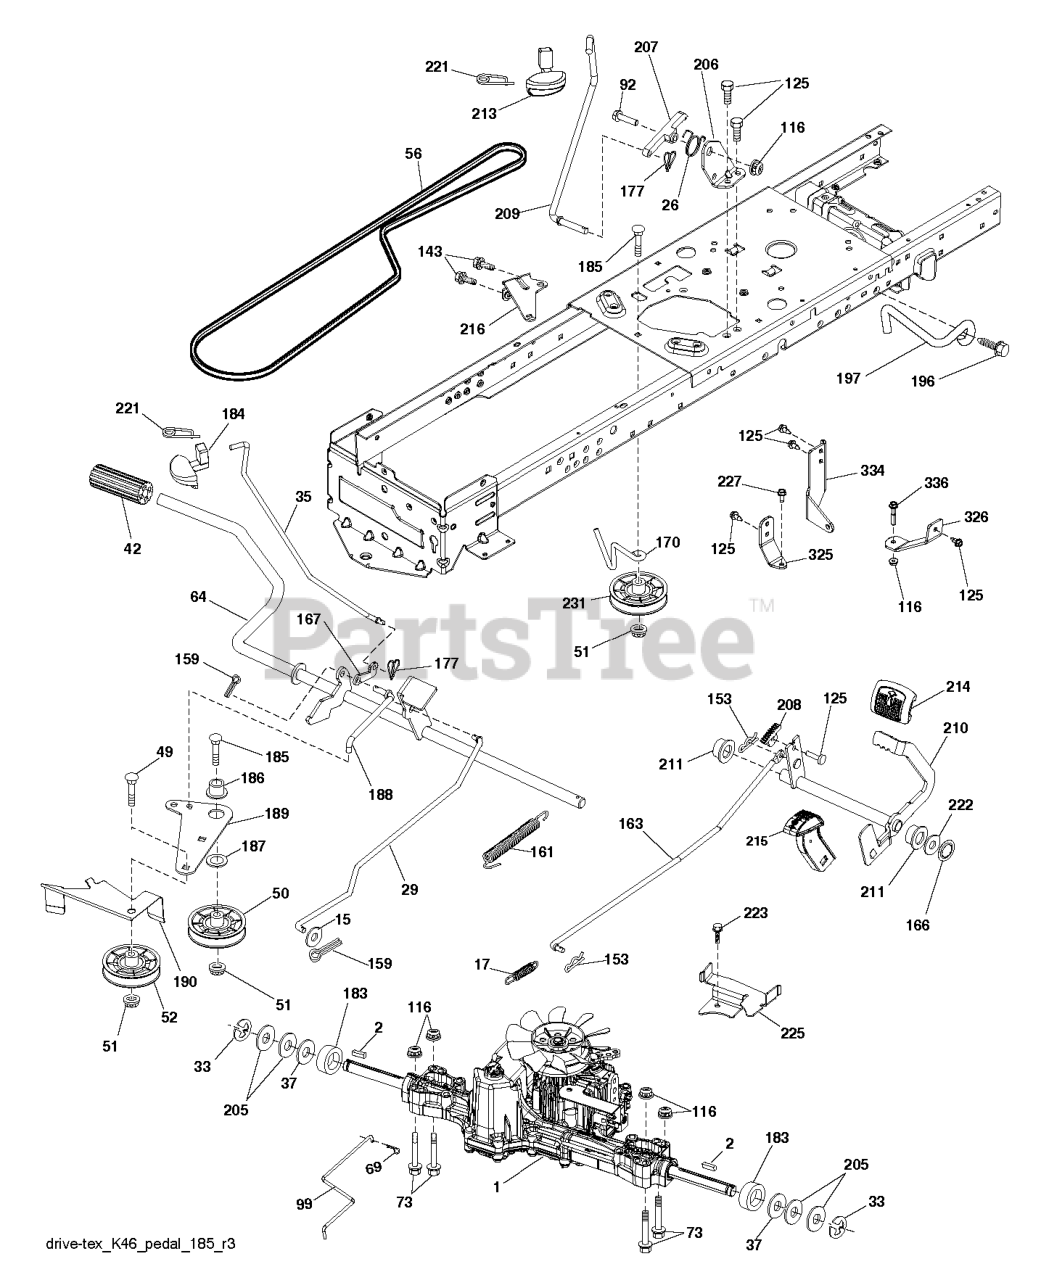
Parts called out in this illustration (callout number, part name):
2	SQUARE KEY
15	WASHER PLAIN WASHER 3/8 X 0.08
17	SPRING.BRAKE.K46.GREEN
26	SPRING.RETURN.CRUISE
29	ROD.BRAKE.K46
35	ROD ROD.PARKINGBRAKE.GT.HUSQ/P
37	WASHER.HARDENED
42	PEDAL COVER
50	IDLER.FLAT.910.OFFSET
51	NUT LOCK FLG 3/8-16 UNC
52	IDLER.V-GROOVE.910.OFFSET
64	SHAFT.ASM.PEDAL.BRK.CNTR
69	HAIRPIN.SOFT.ZINC.059X1.125
99	ARM.PIVOTING.TCRD.GEN2.5.BAGGE
125	SCREW
153	RETAINER M
161	SPRING, RETURN LT
166	NUT.PUSH.625
167	LATCH.BRAKE.SPRING
170	KEEPER.CENTER SPAN.1.688
177	PIN COTTER;LOCKING;BOWTIE;1IN
183	SPACER AXLE
184	HANDLE.PARKING.BRAKE.H (BLK)
186	SPACER.RETAINER
188	LINK.CLUTCH.GROUND DRIVE.LONG
189	BELLCRANK.GROUND.DRIVE.TEX.
190	KEEPER.BELLCRANK.DRIVE
196	SCREW 3/8-16X1
206	BRACKET.MOUNT.CRUISE.LATCH
209	ROD ROD.CRUISECONTROL.GT.HUSQ/
210	ROCKER.ASM.PEDAL.CONTR
211	BEARING.NYLON
213	KNOB.CONTROL.CRUSIE.HU
214	PEDAL.FORWARD.PAD.TEX
215	PEDAL.COVER.REVERSE.CRD.X428BK
216	BRACKET.PULLEY.IDLER.W/TEX
221	RETAINER.SPRING.CLIP.H
222	WASHER 21/32 X 1-1/4 X 10 GA.
225	KEEPER.BELT.TRANSAXLE.K46
231	IDLER.V-GROOVE.1.688.OFFSET
325	TORQUE.STRAP.K46.LT.LH
326	BRCKT.PNT.TRQ.STP.46.18TIRE.RH
334	SWAY.ROD.BRACKET.K46.X431
